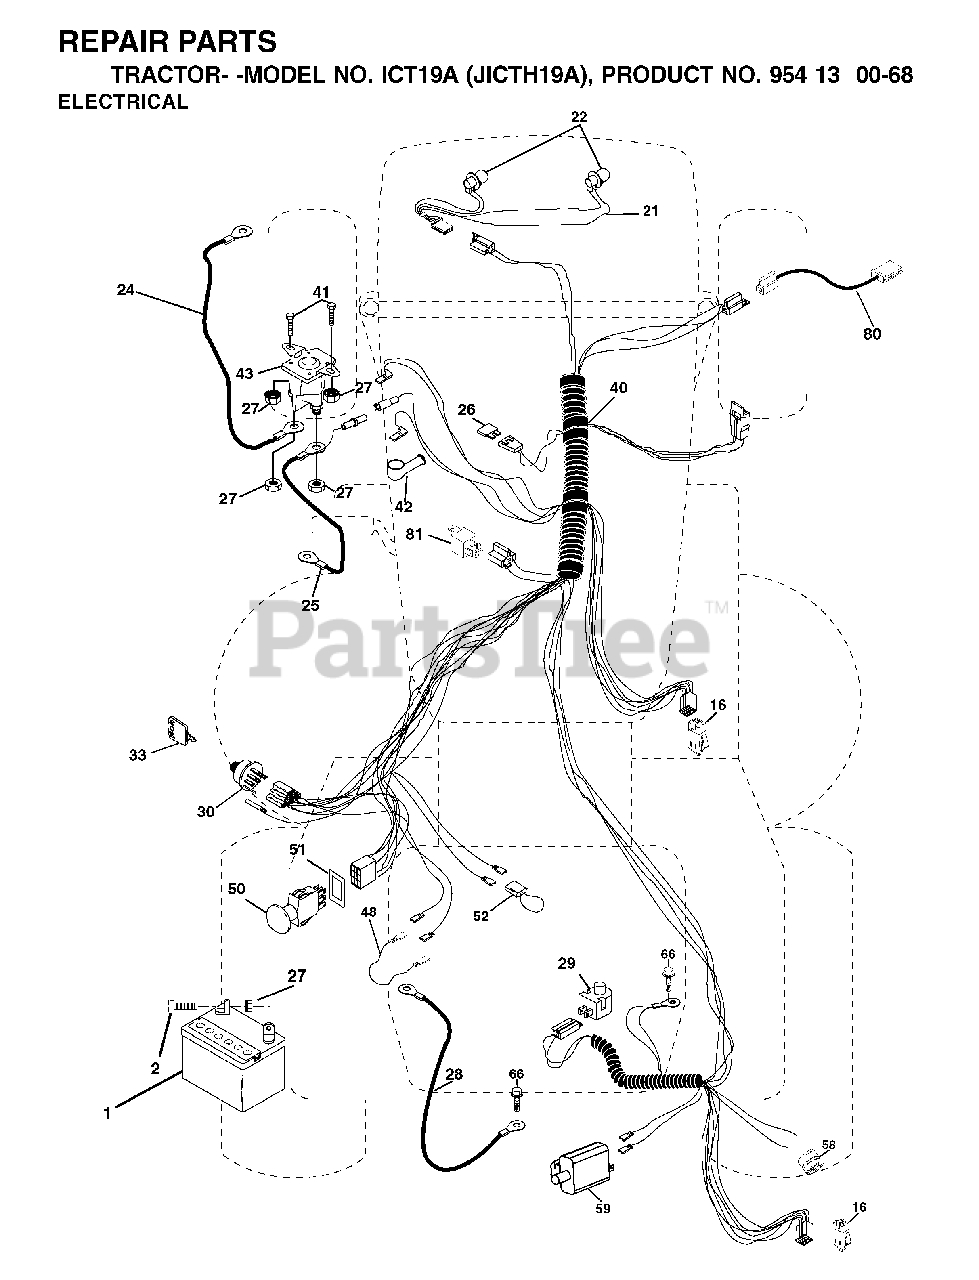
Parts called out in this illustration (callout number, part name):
1	BATTERY 12V .35 AMP
16	SWITCH INTERLOOK PUSH-IN
21	HARNESS.W/LIGHT SOCKET
22	LIGHTBULB
24	BATTERY CABLE GT
25	CABLE BATTERY
26	FUSE 20AMP
27	NUT
28	CABLE GROUND
29	PLUNGER SWITCH (COLOR:OLIVE)
30	IGNITION SWITCH
33	KEY MLD GEN DELTA
42	TERMINAL COVER
43	SOLENOID
50	SWITCH.PTO.8.TERMINAL.
51	RETAINING RING
52	WIRE PROTECTION LOOP
58	BUZZER
80	HARNESS, CLUTCH
81	RELAY.ASSY.T
